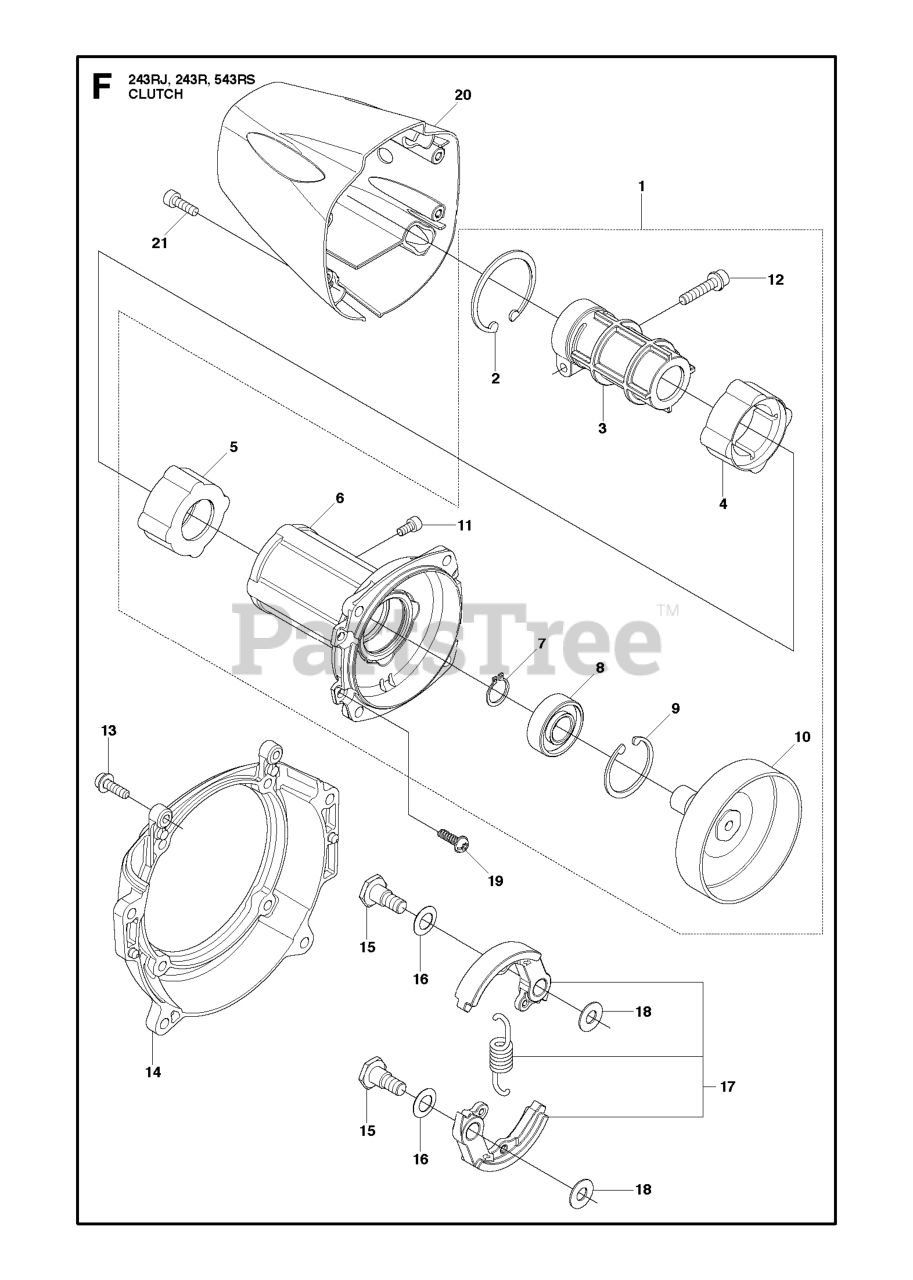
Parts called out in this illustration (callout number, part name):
1	HOUSING ASSY
7	RING, SNAP, M15 x 1.0
8	BEARING 0600406202
10	DRUM
11	BOLT TORX M5XL10 T27
12	BOLT,TORX M6X30
13	BOLT
20	CLUTCH COVER
